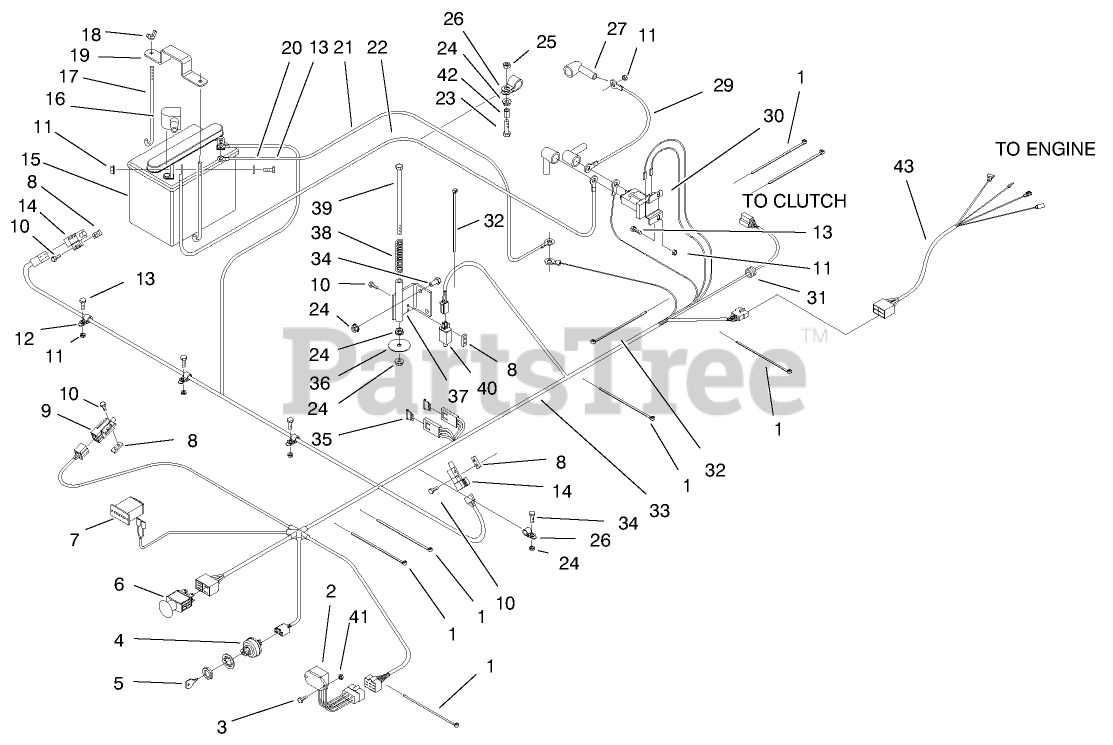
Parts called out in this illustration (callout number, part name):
1	Tie-Plastic
2	Module-Safety
3	Bolt-CARR
4	Ignition Switch
5	KEY-IGNITION
6	Switch
7	Meter-Hour
8	Plate
9	Switch-Brake
10	SCREW-HEAD, PAN
11	NUT-HF
12	Clip
13	SCREW-HH
14	Switch-Drive Lever
15	Battery
16	Insulator Battery
17	Bolt
18	Wingnut
19	Strap-Hold Down
20	WASHER-FLAT
21	Cable-Ground
22	Wire
23	Bolt-TAP
24	NUT-HF
25	Nut-Lock
26	Clip
27	Insulator Solenoid
29	Wire-Starter
30	Switch-Solenoid
31	Grommet
32	Tie-Plastic
33	Harness-Wiring
34	SCREW-HH
35	Fuse
36	Wahser
37	Bracket-Switch, Seat
38	Spring
39	Screw
40	Switch-Seat
41	NUT-LOCK, NI
42	Bushing
43	Harness-Wire
